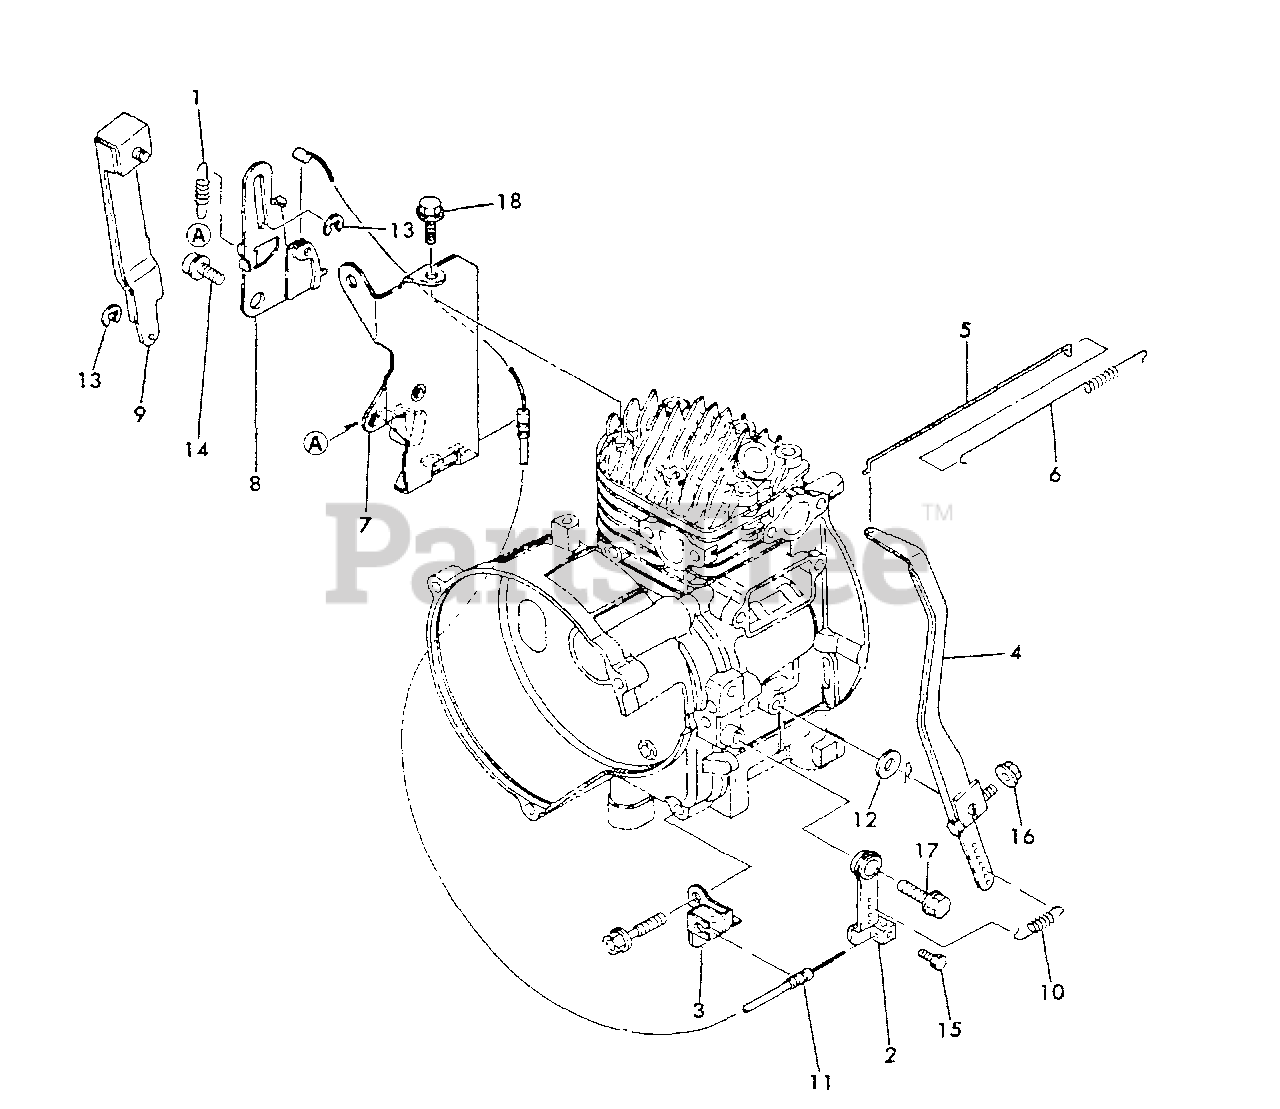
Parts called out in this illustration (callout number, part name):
1	SPRING, REGULATOR
2	HANDLE ASSY
3	WIRE HOLDER
4	LEVER, GOVERNOR
5	LINK, THROTTLE
6	SPRING
7	BRACKET, LEVER
8	LEVER, CONTROL
9	LEVER, CONT. SHIFT
10	SPRING, CONTROL LEVER
11	THROTTLE CABLE ASSY
12	WASHER
13	RING, RETAINING - 5
14	SCREW - 6X10
15	BOLT - 4X8 -- PLATED
16	NUT - 6 -- FLANGE
17	BOLT - 6X8 -- PLATED
18	BOLT - 6X8 -- PLATED
